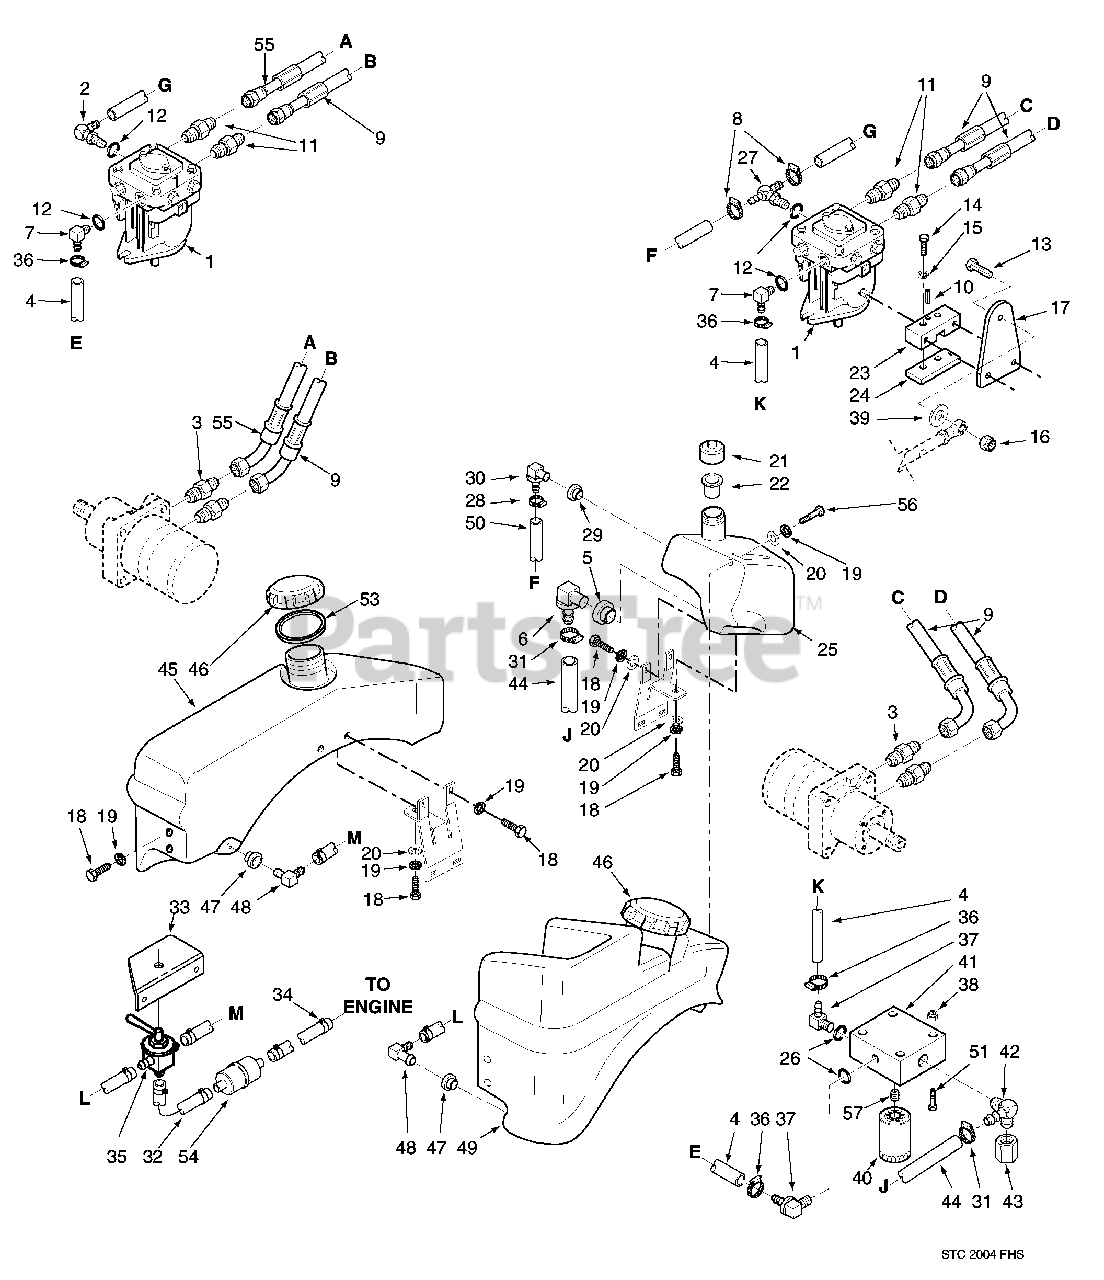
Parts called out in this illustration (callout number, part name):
1	Pump, BDP-10A-316 (L.H.)
2	Elbow, 90 Degree 9/16 O-Ring x 3/8 Hose
3	Fitting, 1/2" JIC x 5/8 O-Ring
4	Hose, 3/8 Pushlock (Specify length)
5	Bushing
6	Fitting
7	Elbow, 90 Degree 9/16 O-Ring x 3/8 Hose
8	Hose Clamp, .69 Dia.
9	Hose Assembly
10	Roll Pin
11	Fitting, 1/2" JIC x 1/2" O-Ring
12	O-Ring
13	Bolt, Hex Head 3/8-16 x 1-1/2"
14	Bolt, Hex Head 1/4-20 x 1-1/4"
15	Lockwasher
16	Nut, Elastic Stop 3/8-16
17	Control Lever
18	Bolt, Hex Head 5/16-18 x 3/4"
19	Lockwasher, 5/16
20	Flatwasher, 5/16-.375 x .875 x .083
21	Cap, Hydraulic Tank
22	Insert, Filler Neck
23	Control Block
24	Clamp Plate
25	Hydraulic Tank Assembly w/fittings
26	O-Ring
27	Tee Fitting, O-Ring to Barb
28	Clamp, .69 Max. / .25 Min. Dia.
29	Bushing
30	Elbow, 0.38 Hose
32	Fuel Hose, 1/4 ID
33	Bracket Fuel Valve
34	Clamp, Fuel Hose 1/4 Hose ID
35	Valve, Fuel Shutoff
36	Clamp, .69 Max. / .25 Min. Dia.
37	Elbow, 1/4 NTP x 3/8 Hose Barb
38	Nut, Serr. Flange 5/16-18
39	Flatwasher, 3/8-.391 x .938 x .105
40	Oil Filter
41	Filter Head Assembly
42	Fitting, Tee Special
43	Cap, 3/4-16 JIC
44	Hose, Filter Inlet
45	Fuel Tank RH
46	Cap, Fuel Tank
47	Tank Bushing
48	Elbow, 90 Degree
49	Fuel Tank LH
50	Hose, 3/8 Pushlock 15" Long
51	Bolt, Hex Head 5/16-18 x 2"
52	Screw, 1/4-20 x 2"
53	Gasket, Gas Tank Cap
54	Fuel Filter
55	Hose Assembly
56	Bolt, Hec Head 5/16-18 x 1-1/2
57	Nipple, Oil Filter 1.0-12 UNF-2A x 1-1/4"
